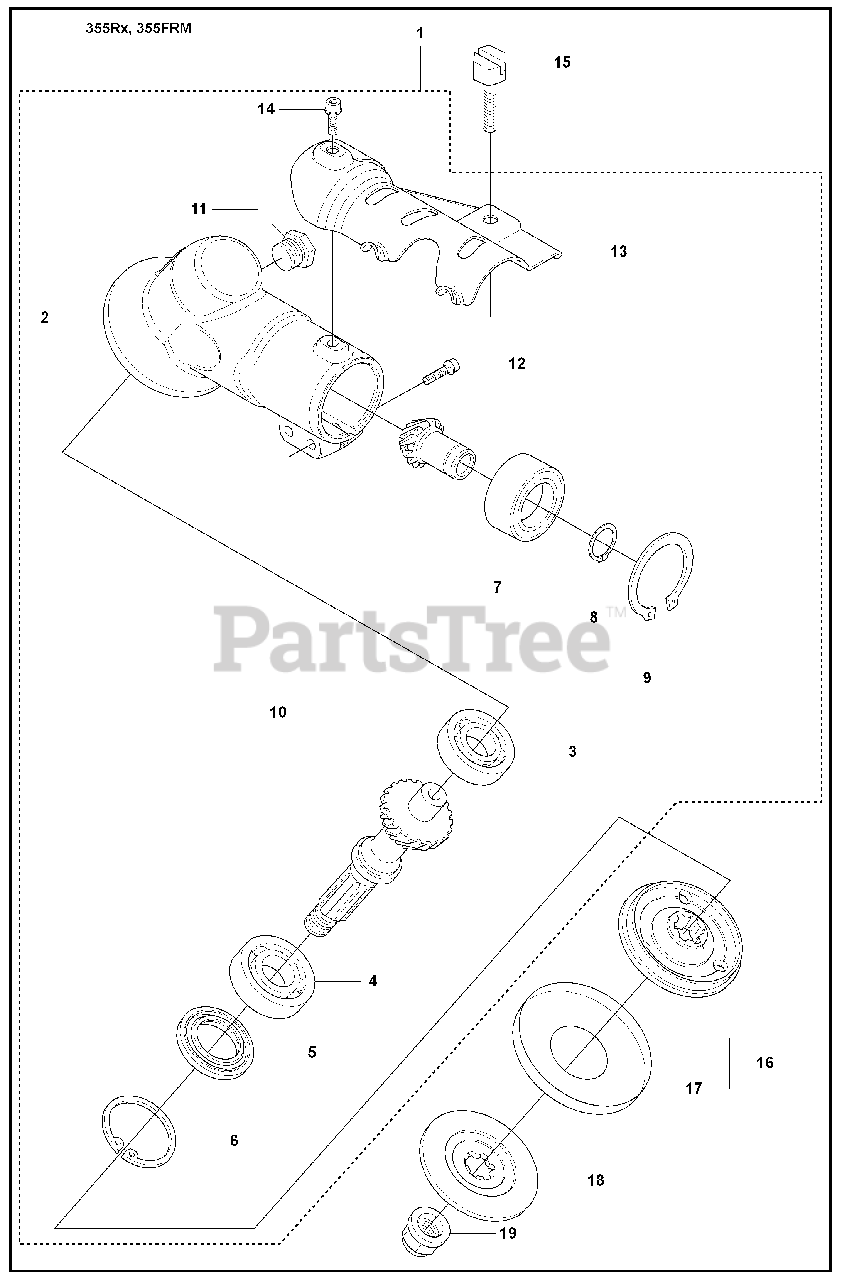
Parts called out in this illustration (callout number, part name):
1	BEVEL GEAR
2	GEAR HOUSING
3	BALL BEARING
4	BALL BEARING
6	RETAINING RING SGH 35
8	RETAINING RING SGA 15
9	RETAINING RING
10	BEVEL GEAR
13	ATTACHMENT PLATE
16	RP CARRIER
17	GRASS SEALING
18	SUPPORT FLANGE
19	BLADE NUT
